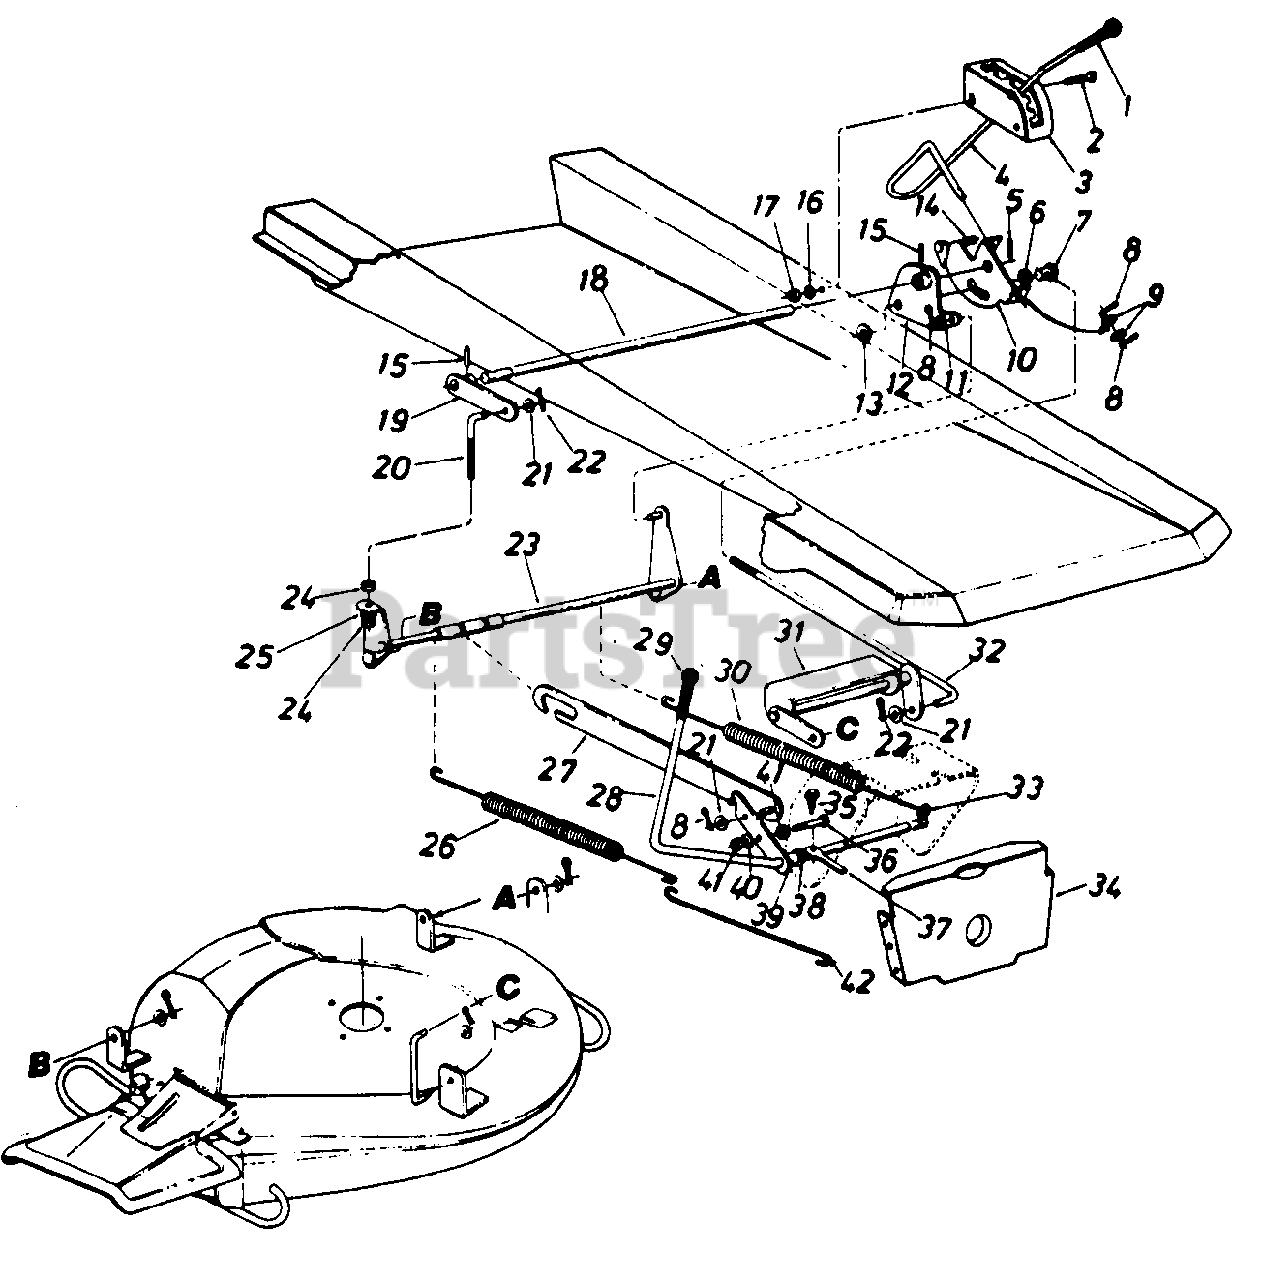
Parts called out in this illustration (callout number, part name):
2	Truss Mach. Scr. 5/16-18 x .75" Lg.
5	Spring Pin Spir. 3/16" Dia. x 1.50" Lg.
6	Fl-Wash. .385" I.D. x .87" O.D.
7	Adj. Ferrule Deck Lift Handle
8	Cotter Pin 1/8" Dia. x 1.00" Lg. *
9	Fl-Wash. .531" I.D. x .930" O.D.
10	Deck Lift Handle Retainer Ass'y.
11	Fl-Wash. .385" I.D. x .87" O.D.
12	Deck Lift Brkt. Ass'y.-L.H.
13	Fl-Wash. .635" I.D. x 1.04" O.D.
14	Compression Spring .50" Dia. x 1.0" Lg.
15	Spring Pin Spir. 1/4" Dia. x 1.50" Lg.
16	L-Wash. 5/16" I.D.*
17	Hex Nut 5/16-18 Thd.*
18	Rear Hgt. Adj. Shaft
19	Deck Lift Brkt. Ass'y.-R.H.
20	Deck Adj. Scr. 3/8-16 Thd.
21	Fl-Wash. .385" I.D. x .87" O.D.
22	Intern. Cotter Pin 1/2" Dia.
23	Deck Link Ass'y.-Rear
24	Hex Nut 3/8-16 Thd.*
25	L-Wash. 3/8" I.D.*
26	Extension Spring .73" O.D. x 1 3.84" Lg.
27	Deck Drive Control Bracket
28	Blade Engagement Lever Ass'y.
30	Extension Spring .73" O.D. x 13.89" Lg.
31	Deck Lift Ass'y.-Front
32	Deck Lift Connecting Rod
33	Clevis Pin Special .250" Dia.
34	Pivot Bar Bracket
35	Hex TT-Tap Scr. 1/4-20 X .75" Lg.
36	Hex Bolt 5/16-18 x 1.50" Lg. (Grade 5)
37	Switch Actuator
38	Fl-Wash. .531" I.D. x .930" O.D.
39	Spacer .511" I.D. x .70" O.D. x.38" Lg.
40	L-Wash. 5/16" I.D.*
41	Hex Nut 5/16-18 Thd.*
42	Spring Hook
